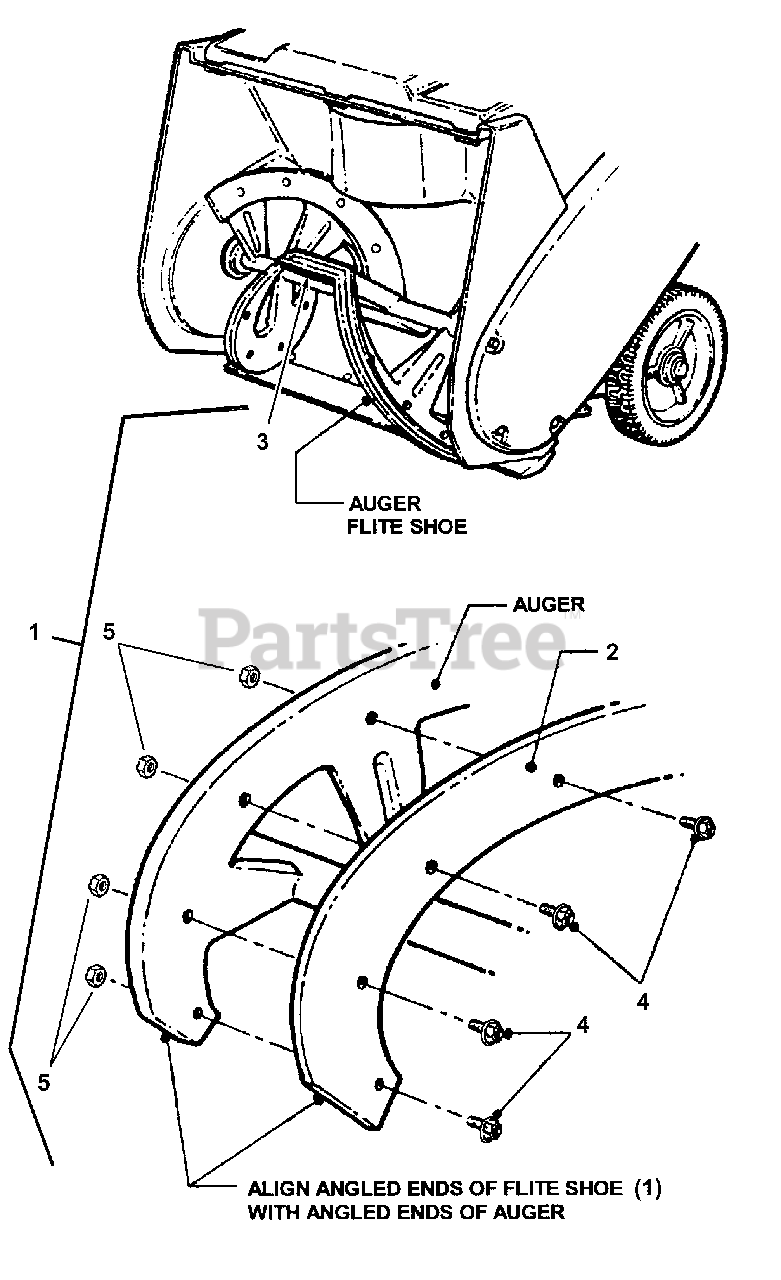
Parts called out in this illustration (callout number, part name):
1	KTI, 19" Flight Shoe (Includes Ref. Nos. 2, 3, 4 & 5)
2	SHOE, 19" Flight Auger
3	SHOE, Fight Center
4	SCREW, Machine 1/4-20 x 1/2
5	NUT, 1/4-20 Hex Center Lock, G5
